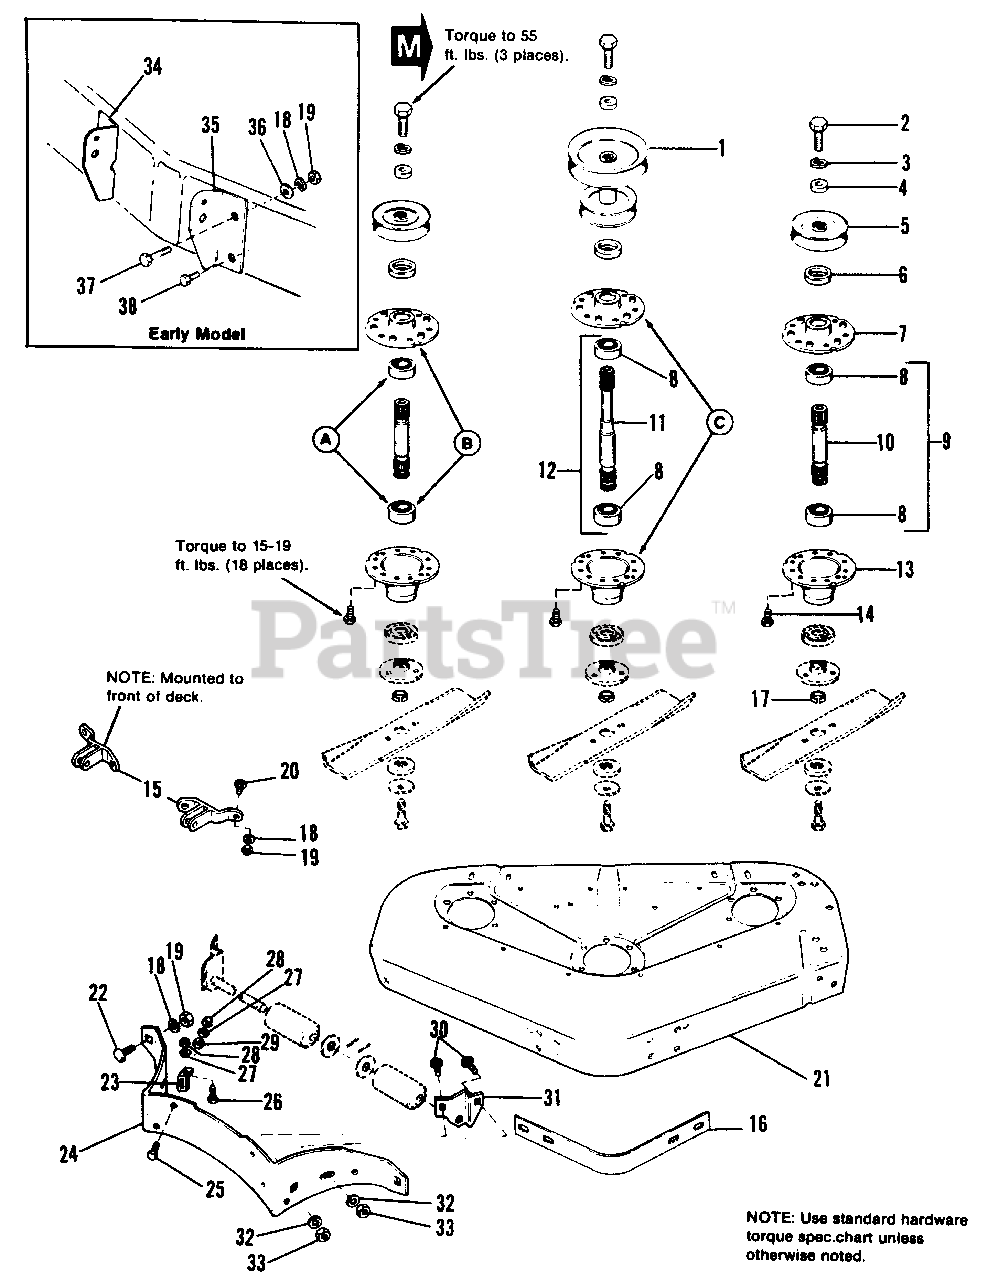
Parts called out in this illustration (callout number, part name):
1	PULLY ASSY.
2	CAPSCREW, Hex Hd., 7/16-14 x 1-1/4
3	LOCKWASHER, 7/16
4	WASHER, Plain, 29/64
5	PULLEY ASSY., Deck Drive
6	SHIELD, Bearing Upper, Arbor
7	HOUSING, Top
9	SHAFT & BEARING ASSY., Side (Includes Ref. Nos. 8, 10 8 17)
10	SHAFT, Arbor, Side (Includes Ref. No. 17)
11	SHAFT, Arbor, Center (Includes Ref. No. 17)
12	SHAFT B, BEARING ASSY., Center (Includes Ref. Nos. 8, 11 8 17)
13	HOUSING, BOTTOM
14	SCREW, Hex Wash. Hd., Taptite, 5/16-18 x 3/4
15	FRONT BRACKET ASSY.
16	BAR, Reinforcement
17	COLLAR, Mower Arbor
18	LOCKWASHER, 3/8
19	NUT, Hex, Full, 3/8-16
20	BOLT, Carriage 3/8-16 x 1-1/4
21	HOUSING, 42"
22	BOLT, Carriage, 3/8-16 x 3/4
23	CLIP, Baffle
24	BAFFLE
25	CAPSCREW, Hex Hd., 1/4-20 x 5/8
26	SCREW, Thd. Cutting, 1/4-20 x 3/4
27	LOCKWASHER, 1/4
28	NUT, Hex, Full, 1/4-20
29	WASHER, Plain, 1/4
30	CARRIAGE BOLT, 5/16-18 x 3/4
31	BRACKET, Roller, L.H.
32	LOCKWASHER, 5/16
33	NUT, Hex, Full, 5/16-18
34	BRACKET, R.H.
35	BRACKET, L.H.
36	WASHER, 13/32
37	CAPSCREW, Hex Hd., 3/8-16 x 1
38	CAPSCREW, Hex Hd., 3/8-16 x 3/4
